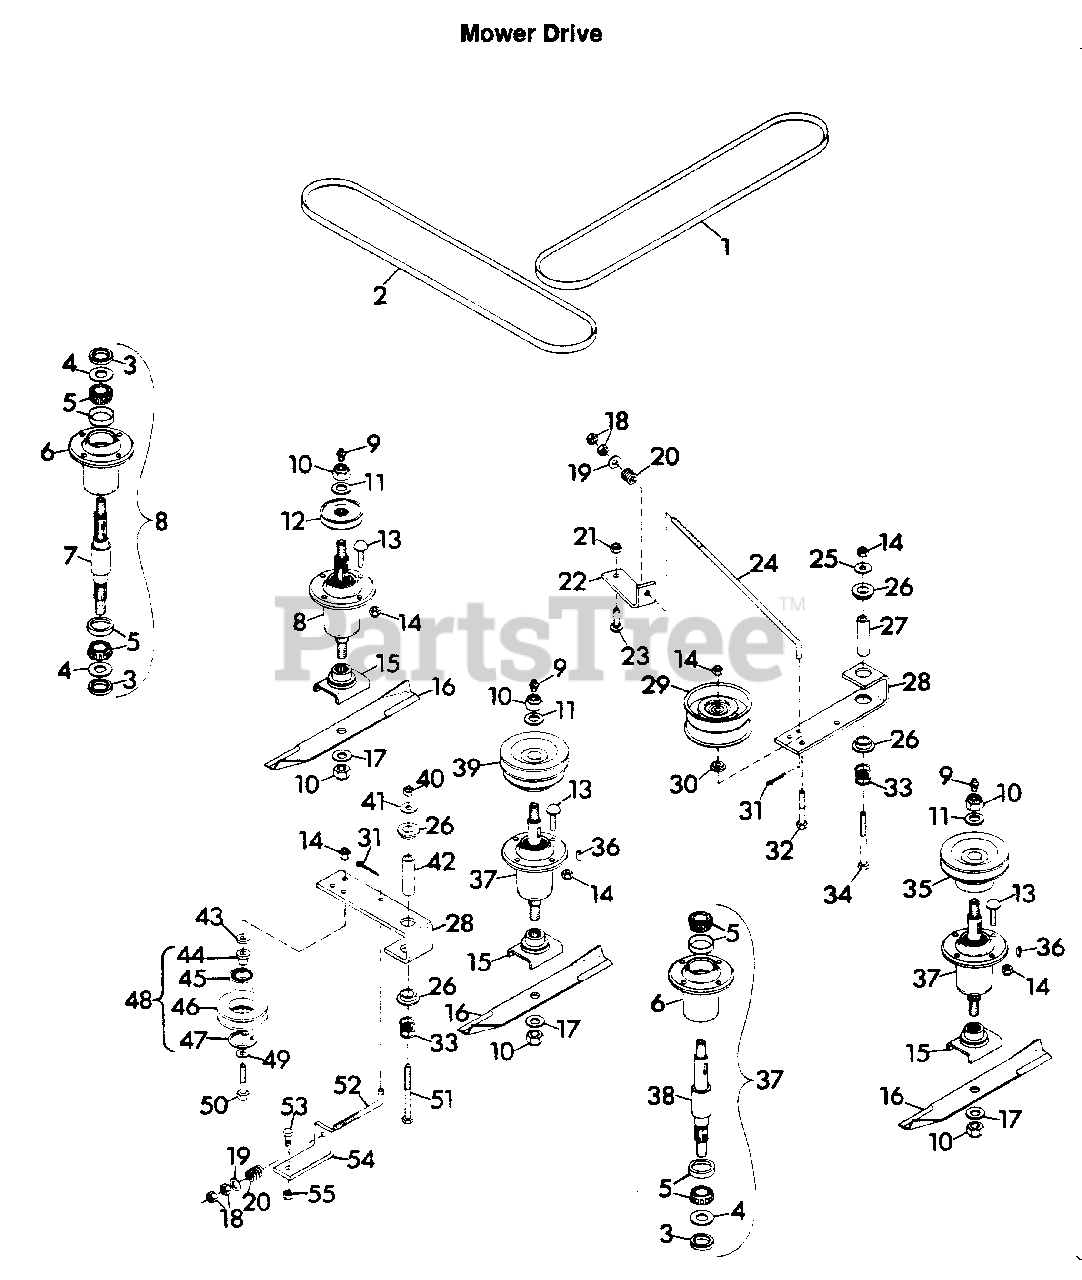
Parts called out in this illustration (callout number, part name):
1	Belt, Pro-40 Mower
2	Belt, Mower A44
3	Seal, Steel(Left & Center Spindles)
3	Seal, Steel(Right Spindle)
4	Washer, Flat .975x1.970x.030(Left & Center Spindles)
4	Washer, Flat .975x1.970x.030(Rt. Spindle)
5	Assembly, Bearing
6	Housing, Bearing
7	Shaft, Spindle
8	Assembly, Spindle
9	Fitting, Lube 1/8
10	Nut, Lock 5/8-11
11	Washer, Flat .687x1.312x.122
12	Sheave, Spindle
13	Bolt 3/8-16x1.25 Rd Hd Sq Nk
14	Nut, Lock 3/8-16
15	Weldment, Blade Cradle
16	Blade
17	Washer, Flat .656x1.312x.095
18	Nut, Hex 3/8-16
19	Washer, Flat .406x.812x.065
20	Spring, Comp. 1x.78
21	Nut, Lock 5/16-18
22	Bracket, Belt Tensioner
23	Bolt, Carriage 5/16-18x1.00
24	Rod, Idler
25	Washer, Flat .438x1.000x.083
26	Bushing, Nylon .76x1x.6 Flg.
27	Spacer
28	Arm, Idler Pivot
29	Pulley, Idler
30	Bushing
31	Pin, Cotter .09x.75
32	Bolt, Hex 3/8-16x2.25
33	Spring, Comp. 1x.80x36 Lb/N
34	Bolt, Hex 3/8-16x3.25
35	Sheave, Spindle
36	Key, Woodruff .250x1 Hard
37	Assembly, Spindle
38	Shaft, Spindle
39	Sheave, Spindle
40	Nut, Lock 1/2-13
41	Washer, Flat .531x1.250x.100
42	Spacer
43	Spacer, Idler .406x.750x.188
44	Bushing, Idler Sheave
45	Bearing, Ball
46	Sheave, Idler
47	Ring, Retaining
48	Assembly, Idler Sheave
49	Washer, Flat .375x1.125x.065
50	Bolt, Hex 3/8-16x2.00
51	Bolt, Hex 1/2-13x3.50
52	Rod, Idler
53	Bolt, Hex 1/2-13x1.25
54	Bracket, Belt Tensioner
55	Nut, Lock 1/2-13
